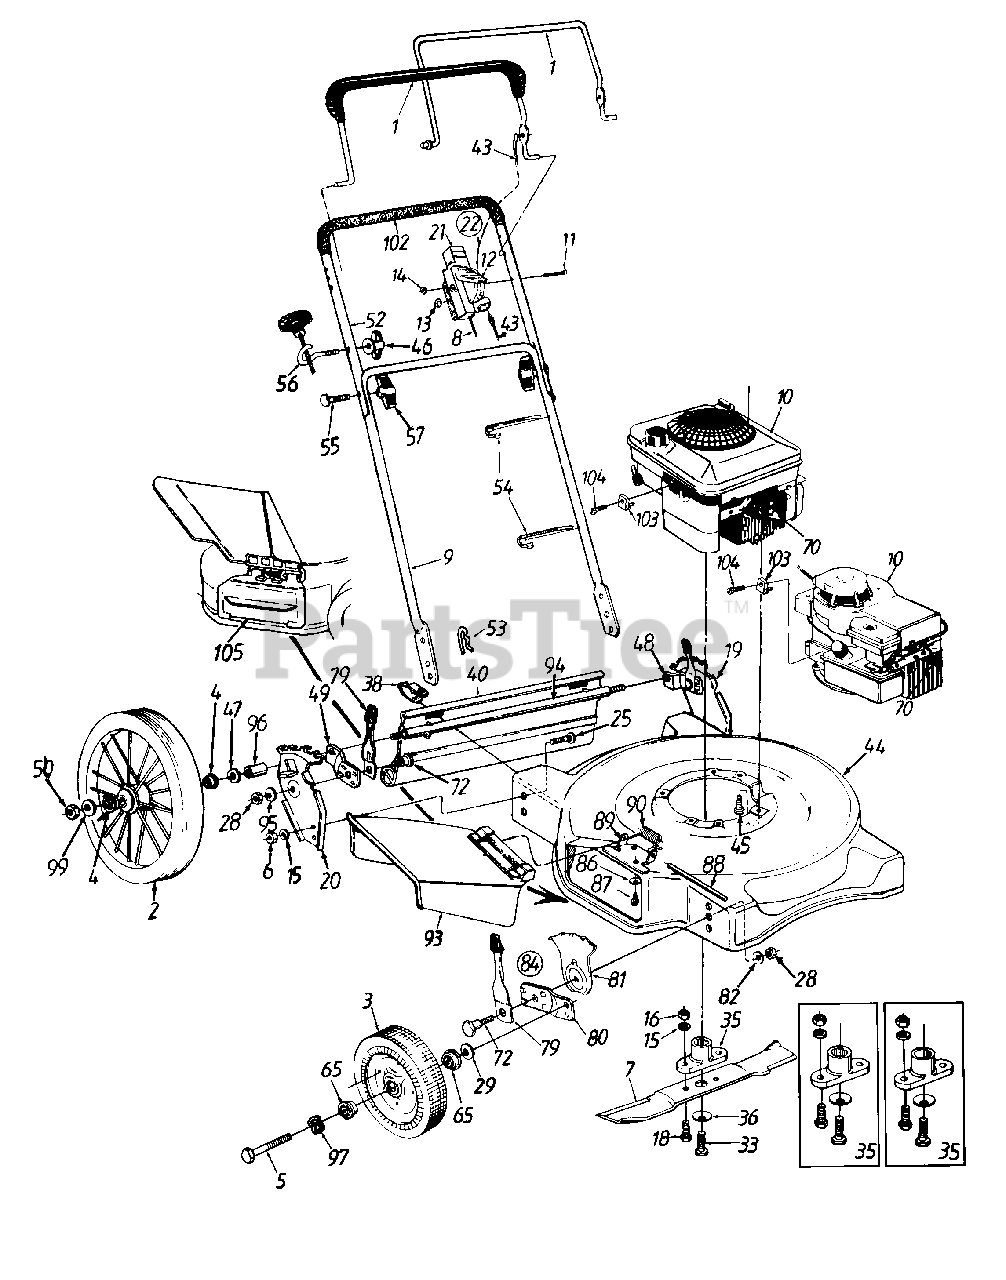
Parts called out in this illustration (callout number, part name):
2	16" Wheel Ass'y.
3	Front Wheel Ass'y.
4	Bearing 1/2" I.D.
5	Front Axle Bolt
6	Hex Nut 3/8-24 Thd. (Gr. 8)
7	22" Blade
8	Throttle Control Wire - 51"
10	Engine
11	Oval C-Sunk Mach. Scr.
12	Throttle Lever
13	Spr. Wash. .66" I.D.
14	Hex L-Nut 1/4-20 Thd.
15	L-Wash. 3/8" I.D.
16	Hex Nut 3/8-24 Thd.
18	Hex Bolt 3/8-24 x 1.0" Lg.
22	Throttle Box Comp.
25	Ribbed Neck Bolt 3/8-24 x .80"
28	Hex Nut 3/8-16 Thd.
29	Bell-Wash..400" I.D. x .88"
33	Hex Bolt 3/8-24 x 1.5" Lg.
35	Blade Adapter Kit
36	Bell-Wash..39" I.D.
38	Hinge Clip
40	Rear Flap Ass'y.
43	Control Cable - 39"
46	Handle Knob 1/4-20 Thd.
47	Wave Wash. .51" I.D.
48	Small Pivot Bar - L.H.
49	Small Pivot Bar - R.H.
50	Mex Jam Nut 3/8-16 Thd.
54	Cable Tie
55	Curved Hd. Bolt 5/16-18 x 2" Lg.
56	Rope Guide
57	Hand Knob
65	Bearing
70	Spark Plug Boot
72	Shoulder Bolt .50" Dia.
79	Spring Lever Ass'y. w/Knob
81	Height Adj. Plate
82	Bell-Wash. .39" I.D. x 1.38"
86	Bell-Wash. .285" I.D. x 75"
87	Hex Wash. Hd. Tap Scr. 1/4-20 x .5" Lg.
88	Hinge Pin
89	Adapter Plate
90	Torsion Spring
93	Chute Deflector Ass'y. Comp.
94	Rear Axle
95	Bell-Wash. 39" I.D. x 1.13"
96	Spacer.55" I.D. x .75"
97	Wave Washer .51" I.D.
99	Fl-Wash. 406" I.D. x .81"
102	Foam Grip
103	Casing Clamp
104	Hex Wash. Hd. Tap Scr. #10-32 x .62" Lg.
105	Mulching Baffle
